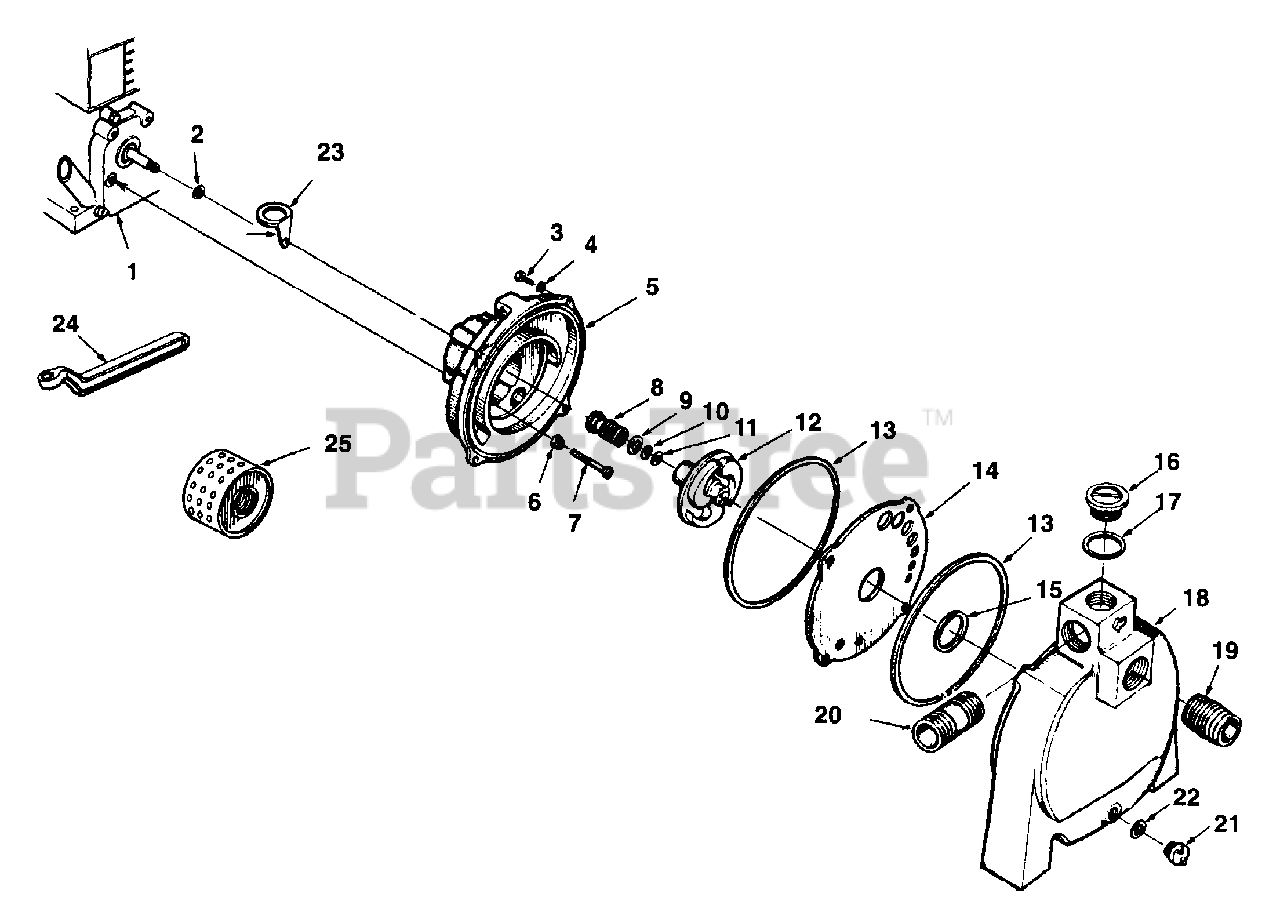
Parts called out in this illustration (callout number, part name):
1	3.5 HP I/P ENGINE
2	SLINGER
3	HEX HD SCREW (5/16-18 X 1.25)
4	LOCK WASHER (5/16)
5	IMPELLER HOUSING
6	SEALING WASHER
7	HEX HD SCREW (5/16-24 X 2.25)
8	SEAL ASSEMBLY
9	SEAL SHIM .010"
10	FLAT WASHER (5/16)
11	IMPELLER SHIM .010"
12	IMPELLER
13	O-RING
14	WEAR PLATE
15	SMALL GASKET
16	FILLER PLUG
17	FILLER PLUG GASKET
18	END HOUSING
19	SUCTION NIPPLE 2" NPT X 2" LONG
20	DISCHARGE NIPPLE 2" NPT X 3 1/2" LONG
21	DRAIN PLUG
23	WRENCH HOLDER
24	SPANNER WRENCH
25	2" SUCTION STRAINER
